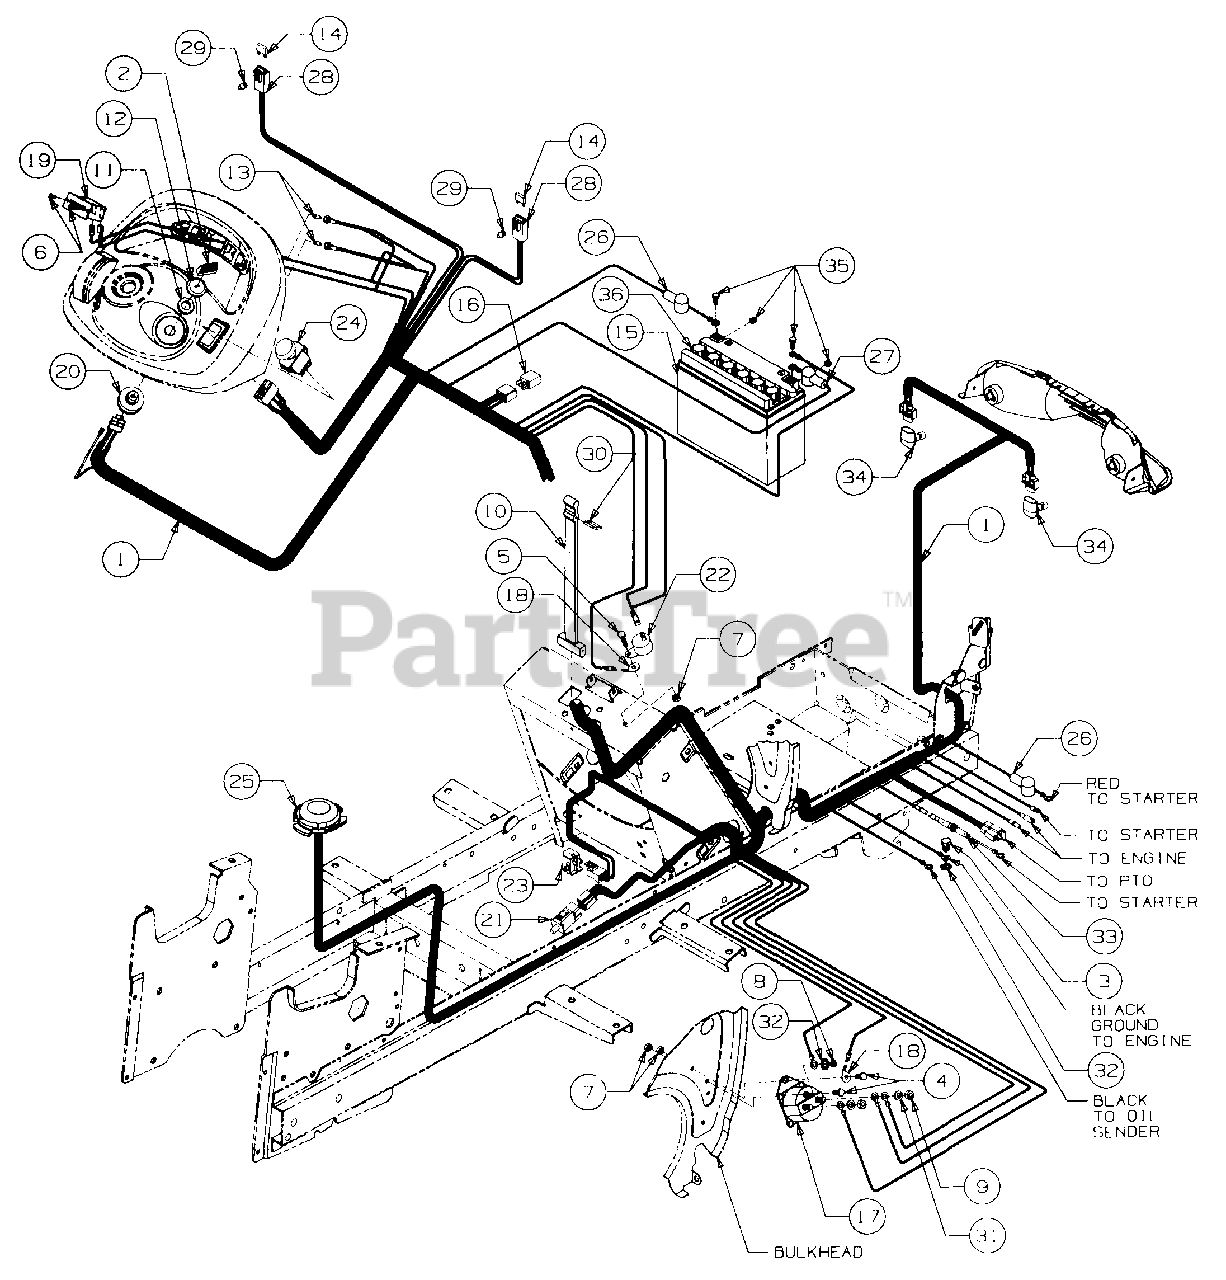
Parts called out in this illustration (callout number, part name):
1	Main Harness
2	Key, Ignition (Set of 2)
3	Screw, Hex Cap, 3/8-16 x .50 Lg GR2
4	Screw, Hex Cap, 1/4-20 x .625 Lg
5	Screw, Hex Cap, 1/4-20 x 1.0 Lg
6	Screw, Truss Hd Tapp, #6 x .62 Lg
7	Nut, Hex Sems, 1/4-20
8	Nut, Hex, #10-32
9	Nut, Hex, 5/16-18 GR5
10	Strap, Battery Retainer
11	Nut, Ignition Switch
12	Cap, Ignition Switch
13	Bulb, Indicator
14	Fuse, 20 Amp
16	Relay
17	Solenoid
18	Lug, Quick Connect
19	Hour Meter
20	Switch, Ignition
21	Switch, Interlock (Brake)
22	Indicator, Voltage
23	Switch, Snap Mount - Normally Closed (Reverse)
24	Switch, PTO
25	Switch, Seat
26	Cover, Terminal Red
27	Cover, Terminal Black
28	Holder, Fuse
29	Clip, Fuse Holder Mtg
30	Hook, Wire Rectangular
31	Washer, Lock, 5/16
32	Washer, External Lock, 3/8
33	Diode Assy w/Lead
34	Bulb, Head Lamp
35	Bolt, Battery (Set of 2)
36	Cap, Battery
